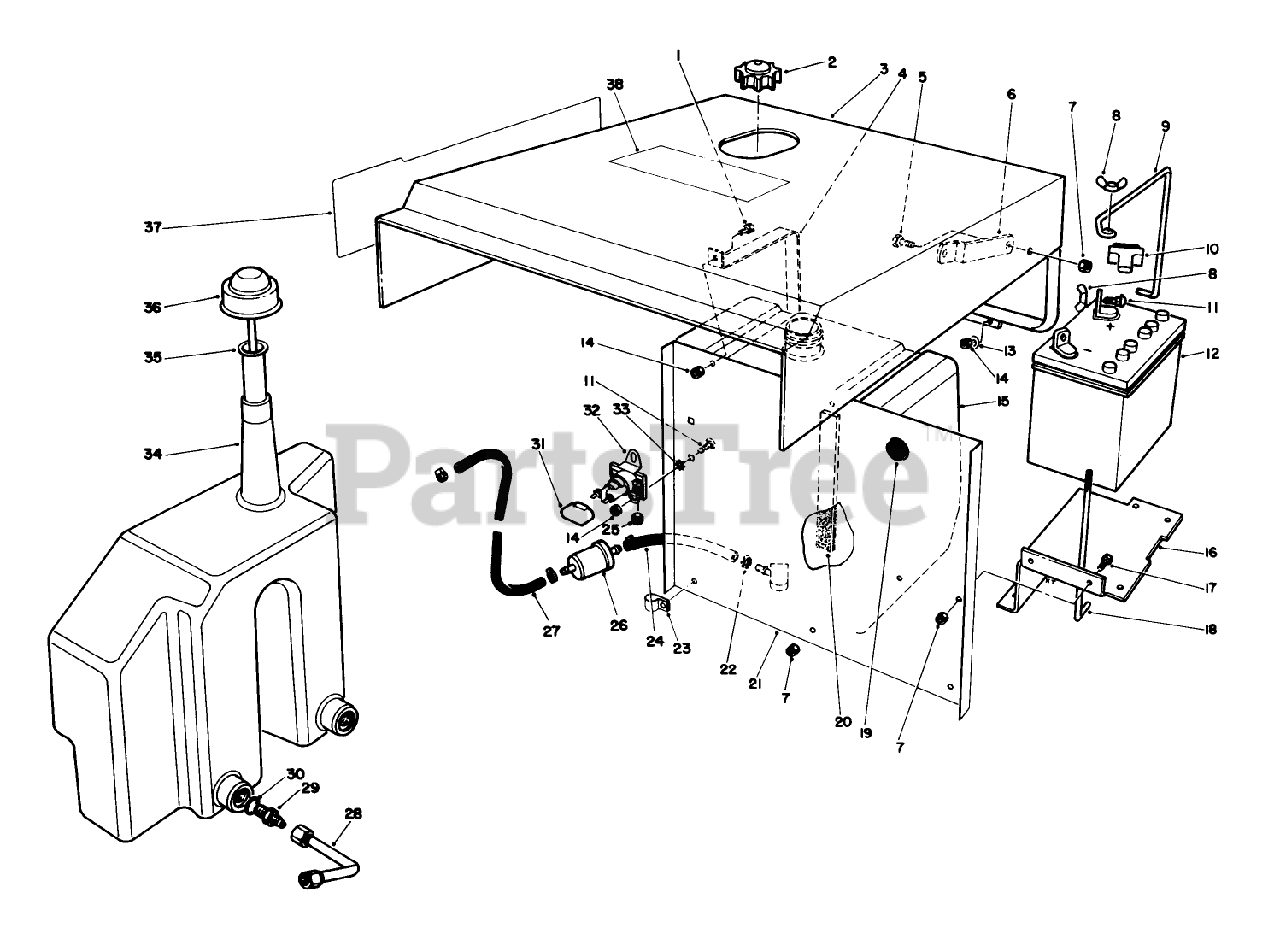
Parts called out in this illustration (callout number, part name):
1	SCREW-HH
2	GAS CAP ASM
5	SCREW-HH
6	UPPER HOOD STOP
7	NUT-LOCK, NI
8	NUT-WING
9	BATTERY CLAMP
10	BOOT-TERMINAL
11	BOLT-CARR
12	SEE SB MISC 14
13	WASHER-FLAT
14	NUT-LOCK, NI
15	TANK-FUEL
17	SCREW-HH
18	ROD-SUPPORT, BATTERY
19	GROMMET
20	TANK SPONGE
22	CLAMP-HOSE
23	CLAMP-R
25	NUT-HEX
28	TUBE ASM
29	FITTING-STRAIGHT
30	O-RING
33	WASHER-LOCK/EXT
34	OIL RESERVOIR
35	SCREEN-FILLER
36	CAP WA
38	DECAL-REFUELING
